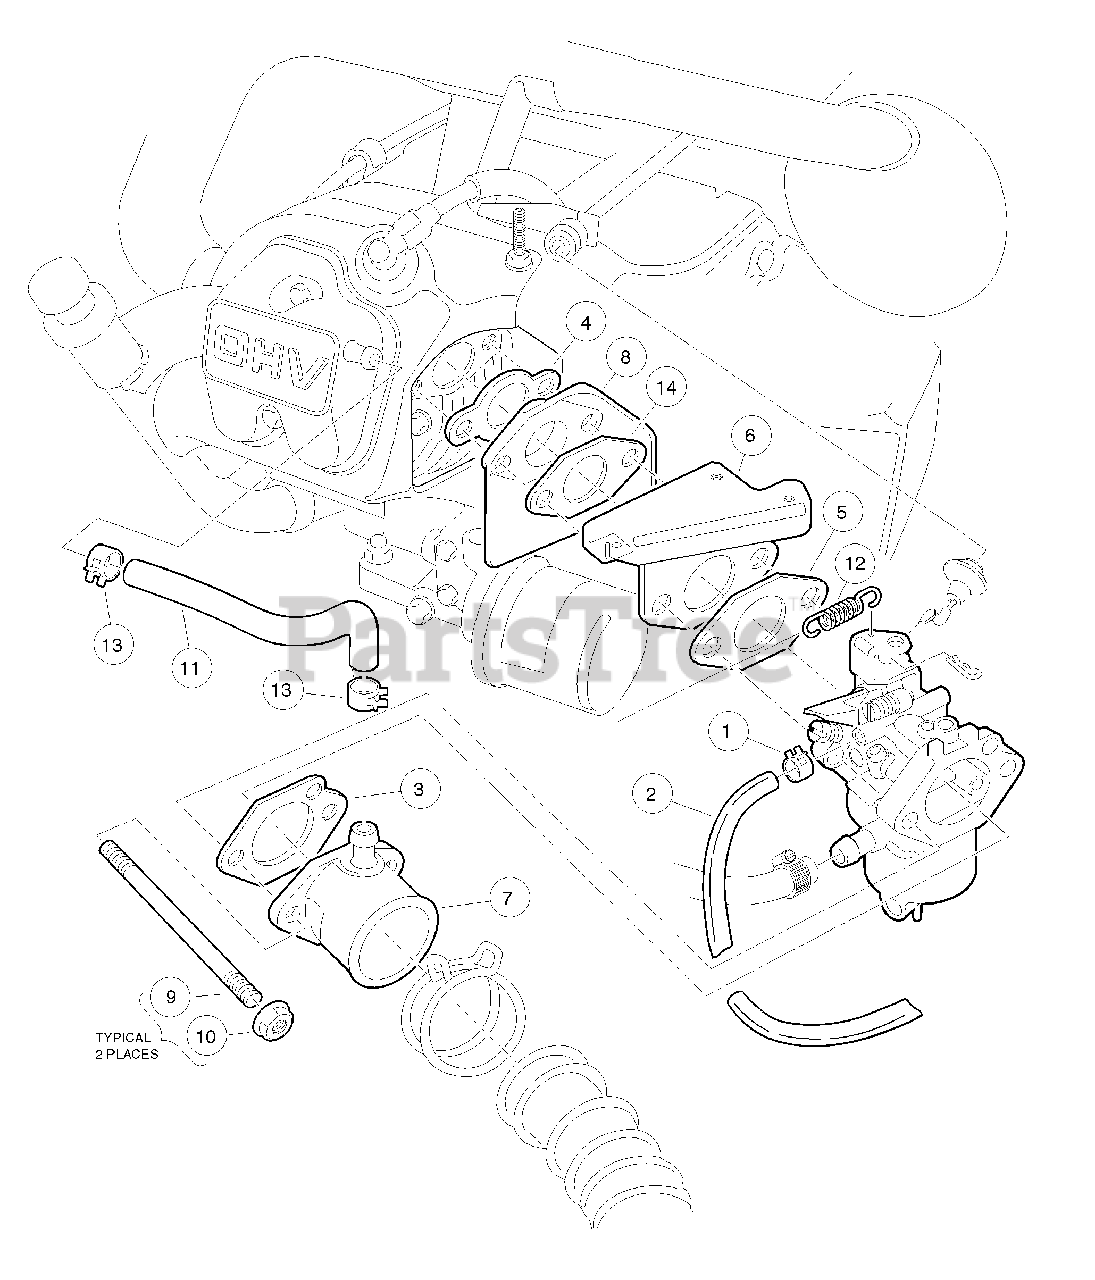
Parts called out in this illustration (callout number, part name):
1	Clamp, 0.301 ID Hose
2	Fuel Line
3	Gasket, Carb To Intake Manifold
4	Gasket, Engine to Insulator
5	Gasket, Sprg Brkt To Carb OHV
6	Bracket, Throttle Spring Return
7	Pipe, Intake Manifold
8	Insulator, Carburetor
9	Stud, M6-1.00 Two-Ended
11	Tube, Crankcase Vent
12	Spring, Throttle Return
14	Gasket, Insulator To Bracket
